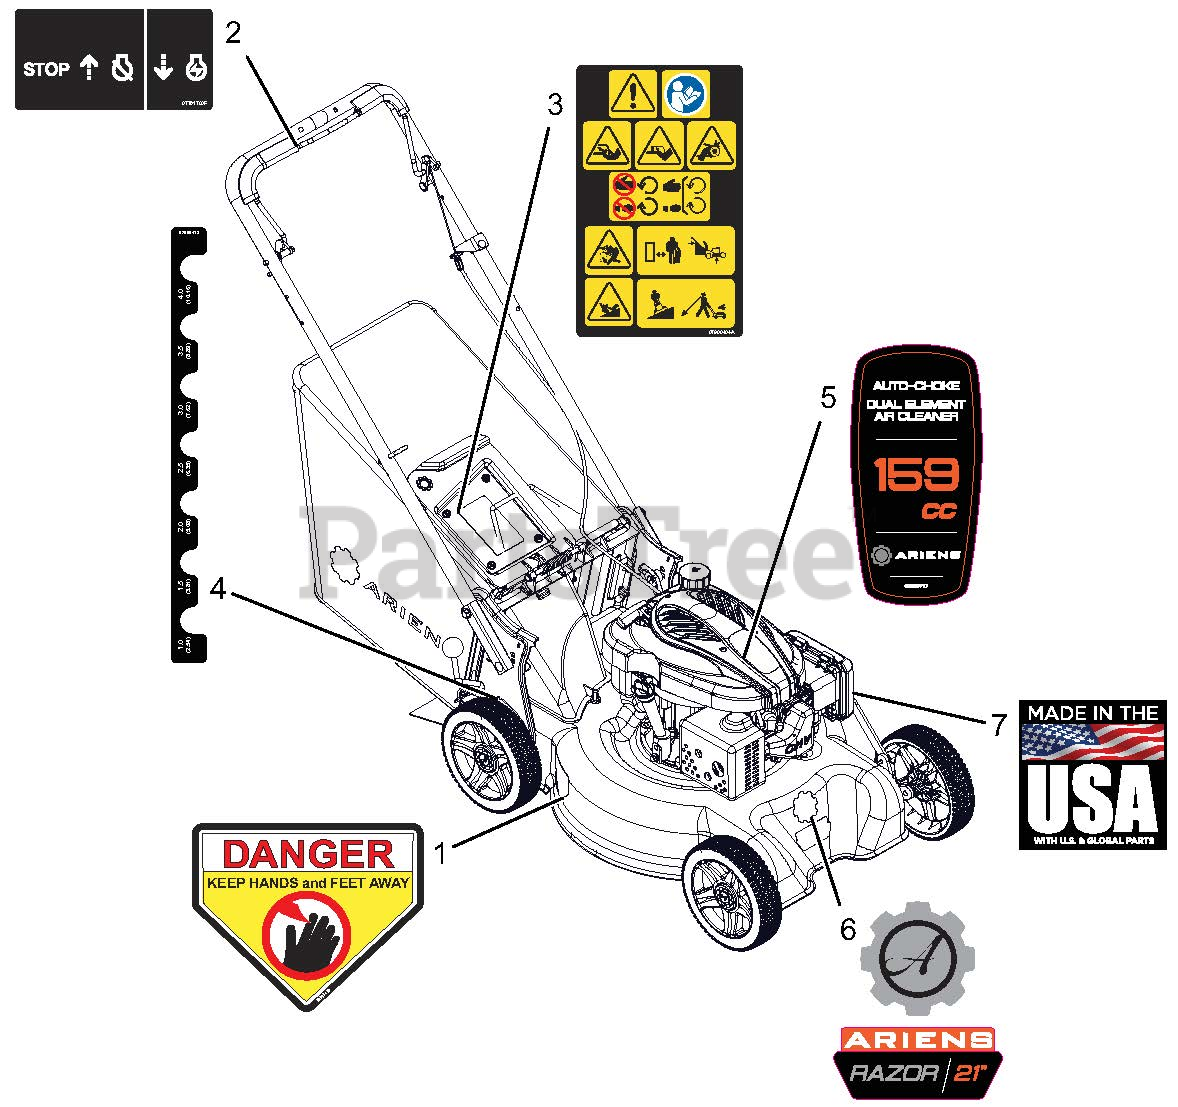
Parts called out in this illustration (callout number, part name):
1	DECAL, DANGER
2	DECAL - ENGINE CONTROL
3	DECAL,MAIN SAFETY_WAW LM
4	DECAL, HOC
5	DECAL-ENGINE STYLE-RAZOR
6	DECAL-ARIENS RAZOR 21"
7	DECAL, MADE IN USA
